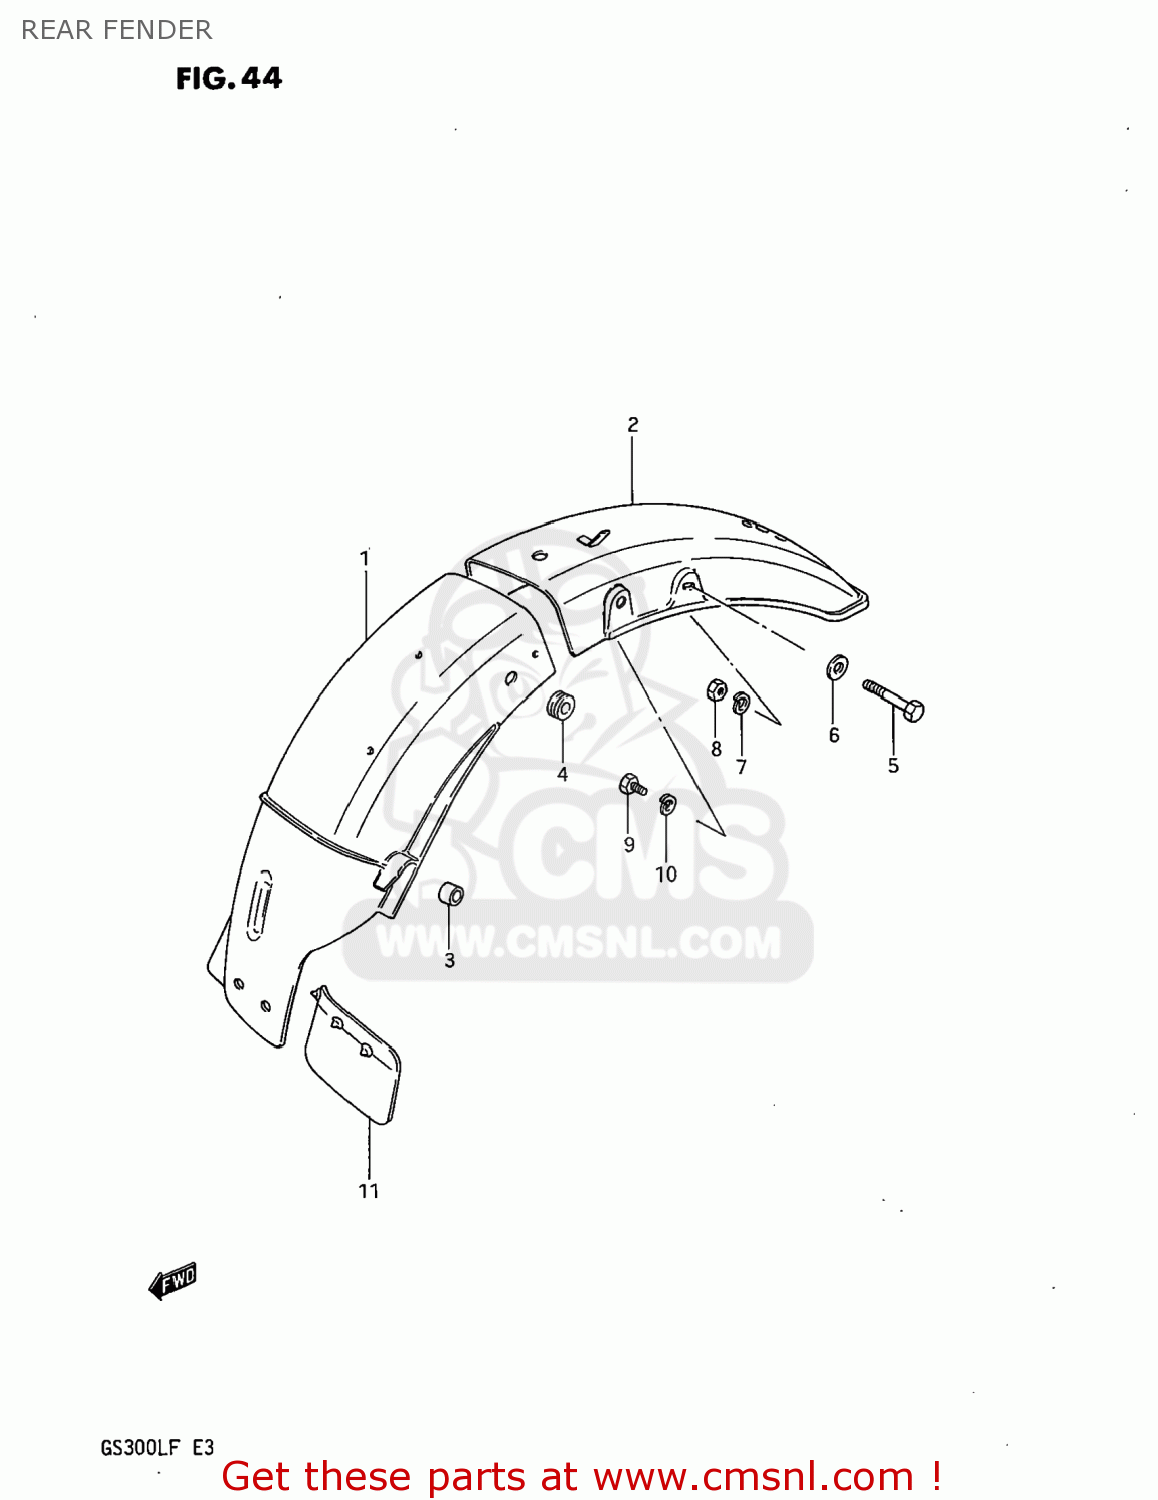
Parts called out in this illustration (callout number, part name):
1	FENDER,REAR
2	FENDER,REAR
3	CUSHION
4	CUSHION
5	BOLT
6	WASHER
7	LOCK WASHER
8	NUT
9	BOLT
10	LOCK WASHER
11	GUIDE,RR FENDER MUD
